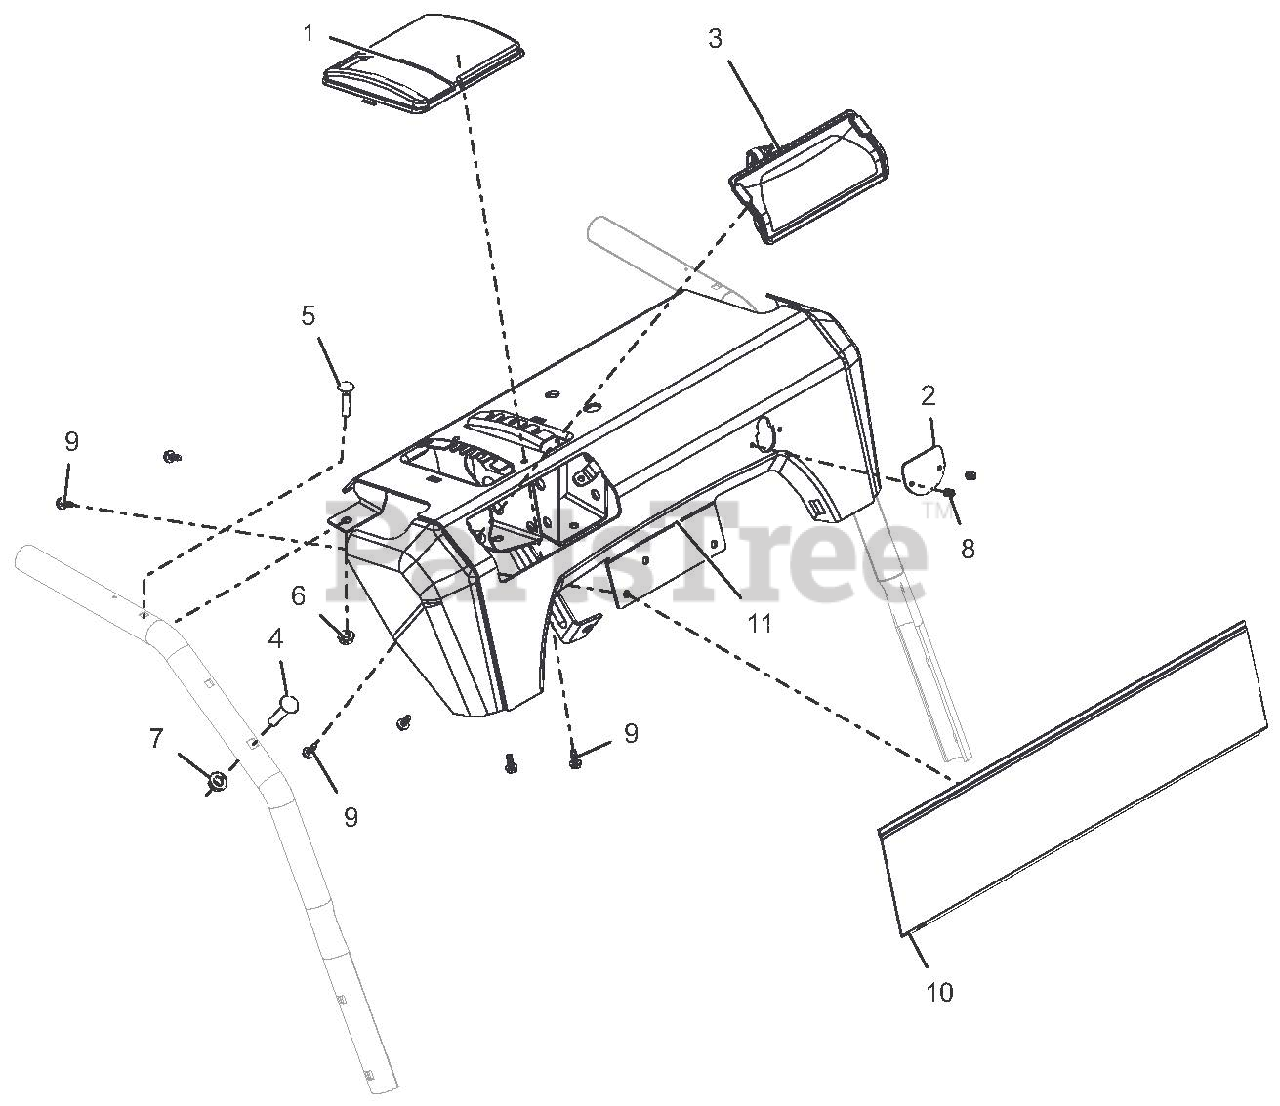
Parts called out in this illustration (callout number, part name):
1	BEZEL, SHIFT - FRICTION BRUSH
2	COVER, DASH BRKT, BRUSH (BLACK)
3	ASM, HEADLAMP - HALOGEN 15W - 2 SHOT
4	BLT-RDHDSQNK .31-18X1.50 G5 YWZC
5	BLT, RDHDXLSQNK .25-20X1.25 G5YZ
6	NUT, LK-CTR-FLG .25-20 YWZC
7	NUT, LK-TOP-FLG .312-18 YWZC
8	RVT-POP #43 .125x.313 STL ZINC
9	SCR-TAP #10X.500 BOSS INDHXHD
10	WLDMT, BRAND PLATE
11	DASH, SERVICE - 08000740 DECAL
